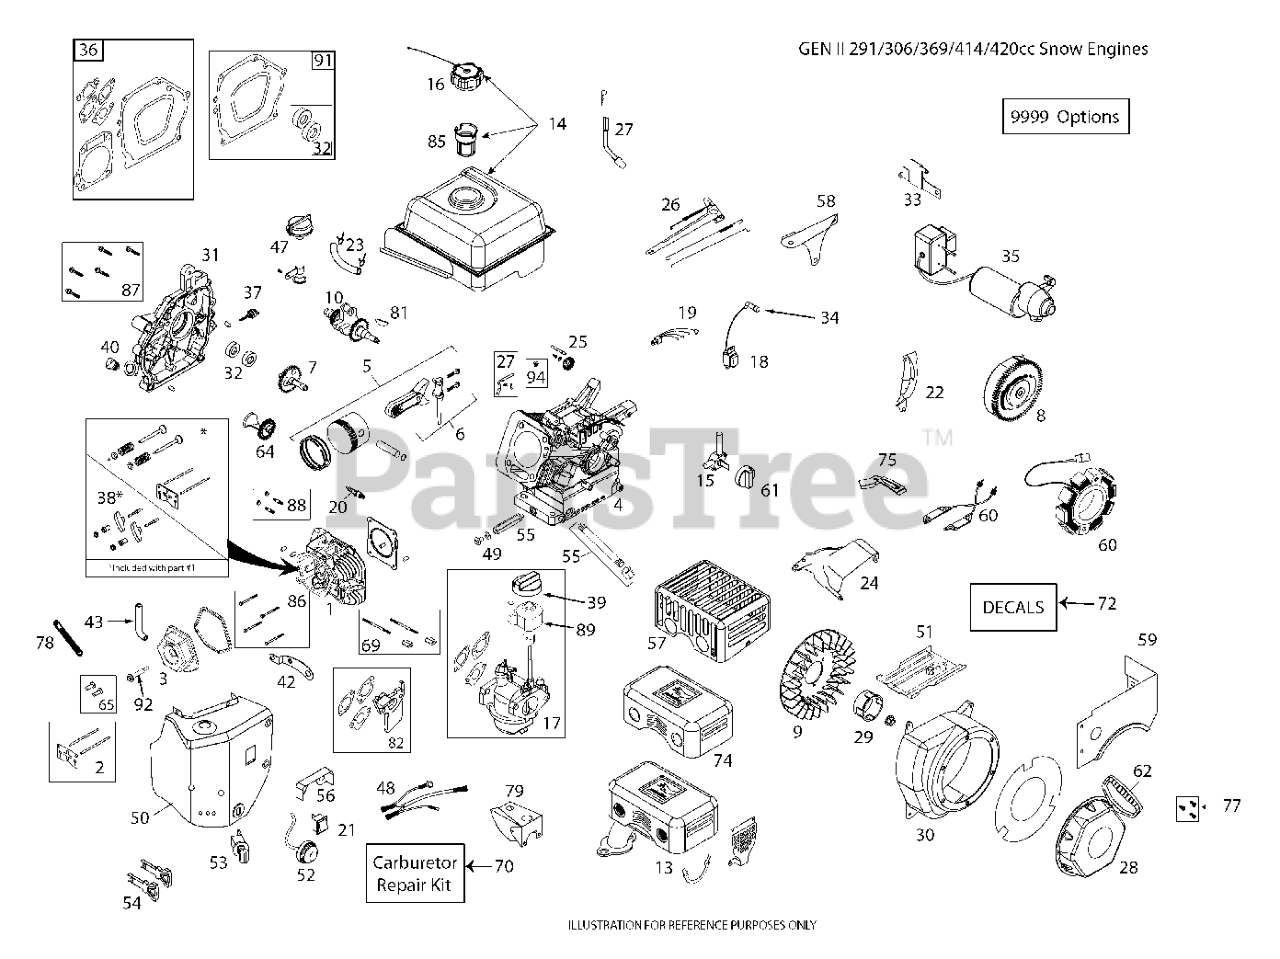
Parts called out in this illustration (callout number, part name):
1	CYLINDER HEAD LCT 178 INCLUDES
2	PUSH ROD TAPPET KIT
3	VALVE.COVER.LCT.414CC.
5	PISTON ROD ASM.LCT SK3691400.1
7	CAMSHAFT(SK4141600)
8	FLYWHEEL.EL.ST.SKSN4408.1
9	FLYWHEEL.FAN(SK4144000)
10	CRANKSHAFT KEYED #18 LCT 414C
13	MUFFLERS
13	MUFFLER ASSY LCT SNO
14	FUEL.TANK.ASSY.SNOW(SKSN4300)
15	FUEL.PETCOCK.SNOW(SKSN4900)
16	FUEL.TANK.CAP.SNOW(SKSN4301)
17	CARBURETTOR L18D LCT 369
17	CARBURETORS
18	IGNITION.COIL.(CDI).291-414CC
20	SPARK.PLUG(2083810)
21	ON/OFF.SWITCH.SNOW(SKSN4403)
22	SHIELD.U/FYWHL.CHARG(SKSN4604)
23	FUEL HOSE KIT
24	Husqvarna TBD
24	RP TOP SHIELD
24	CONTROL.SPEED.FIXED.LCT.SKSN44
25	GOVERNOR.GEAR.ASSY(SK4142900)
26	GOVERNOR.ARM.ASSY(SKSN4502)
27	GOVERNOR.SHAFT(SK4143100)
29	STARTER CUP
30	BLOWER LCT 414CC
31	CRANKCASE.COVER.LCT.414CC.HIGH
31	CRANKCASES
32	OIL SEAL KIT NON-GENERATOR
33	ELECTRIC.START.BRKT(SKSN4405)
34	SPARK.PLUG.BOOT.SNW,SKSN4691.1
35	STARTER EUROPEAN 230V ELECTRIC
35	ELEC.START.ASSY.SNOW(SKSN4400)
36	GASKET KIT ENGINE LCT 369
37	DIPSTK.OIL.BLK.LCTSK4143711.1
38	ROCKER ARM KIT
39	CHOKE.KNOW.SNOW(SKSN4500)
40	NONREMVABLE.OIL.PLUG(SK4143715
43	BREATHER TUBE LCT 291/369/414
47	HIGHOIL.FILL.ASSY.KIT(SKSN4911
48	WIRE.HARNESS.SNOW
48	HARNESS WIRE. W/O OFF/ON SWITC
49	OIL.DRAIN.PLUG
50	HEATER.BOX.ASSY-SNW(SKSN4100)
50	CARBURETORS
51	SHIELD.CYLINDER.SNOW(SK4141010
52	PRIMER.BULB.ASSY(SKSN4304)
53	KEY.SWITCH.ASSY.SNOW(SKSN4401)
54	KEY SET(2 KEYS) SKSN0407.1
55	OIL PIPE DRAIN EXTENDED.LCT SK
56	SHIELD.VAPOR(SKSN4606)
57	CE COMPLIANT MUFFLER SHEILD
58	SHIELDS
58	PLATE.GOVERN.LINK.S
59	FUEL TANK SKIRT.LCT.369/420CC
60	ALTERN.60WATT.SKSN2402.1
61	FUEL KNOB-SNOW
62	HANDLE.RECOIL.DELUXE.LCT
64	COUNTER WEIGHT KIT
65	TAPPET KIT.LCT.SK2911005.1
69	STUD.CARB.MOUTING.KIT.414CC
70	CARBURETTOR REPAIR KIT 291CC/4
72	ARIENS 414 SNOW DECAL KIT
74	MUFFLER SHIELD
75	SHIELD.U/FYWHL.CHARG(SKSN4604)
77	BOLT.KIT.RECOIL.LCT.ALL.ENGINE
78	STRAP.RETAINING.TUBE.BREATHER.
81	KEYS.FLYWHEEL.208/414CC.5PACK
82	SPACER.CARBURETOR.414CC.LCT
85	STRAINER.FUEL.TANK.LCT.208CC
86	KIT.BOLT.CYLINDER.HEAD.(4PC)
87	KIT.BOLT.CRANKCASE.COVER.414CC
88	STUD.MUFFLER.KIT.LCT
89	KNOB LCT.SKSN5325.1 SPEED
91	GASKET KIT CRANKSHAFT.LCT
92	CENTER VALVE COVER BOLT
94	SEAL GOVERNOR SHAFT OIL.LCT
97	GUARD.EXHAUST
9999	HIGH ALTITUDE JET 6000FT
9999	KIT.BOLT.LCT.SK9990.1
9999	STARTER SCREW.STARTER SWITCH B
9999	CLIPS
